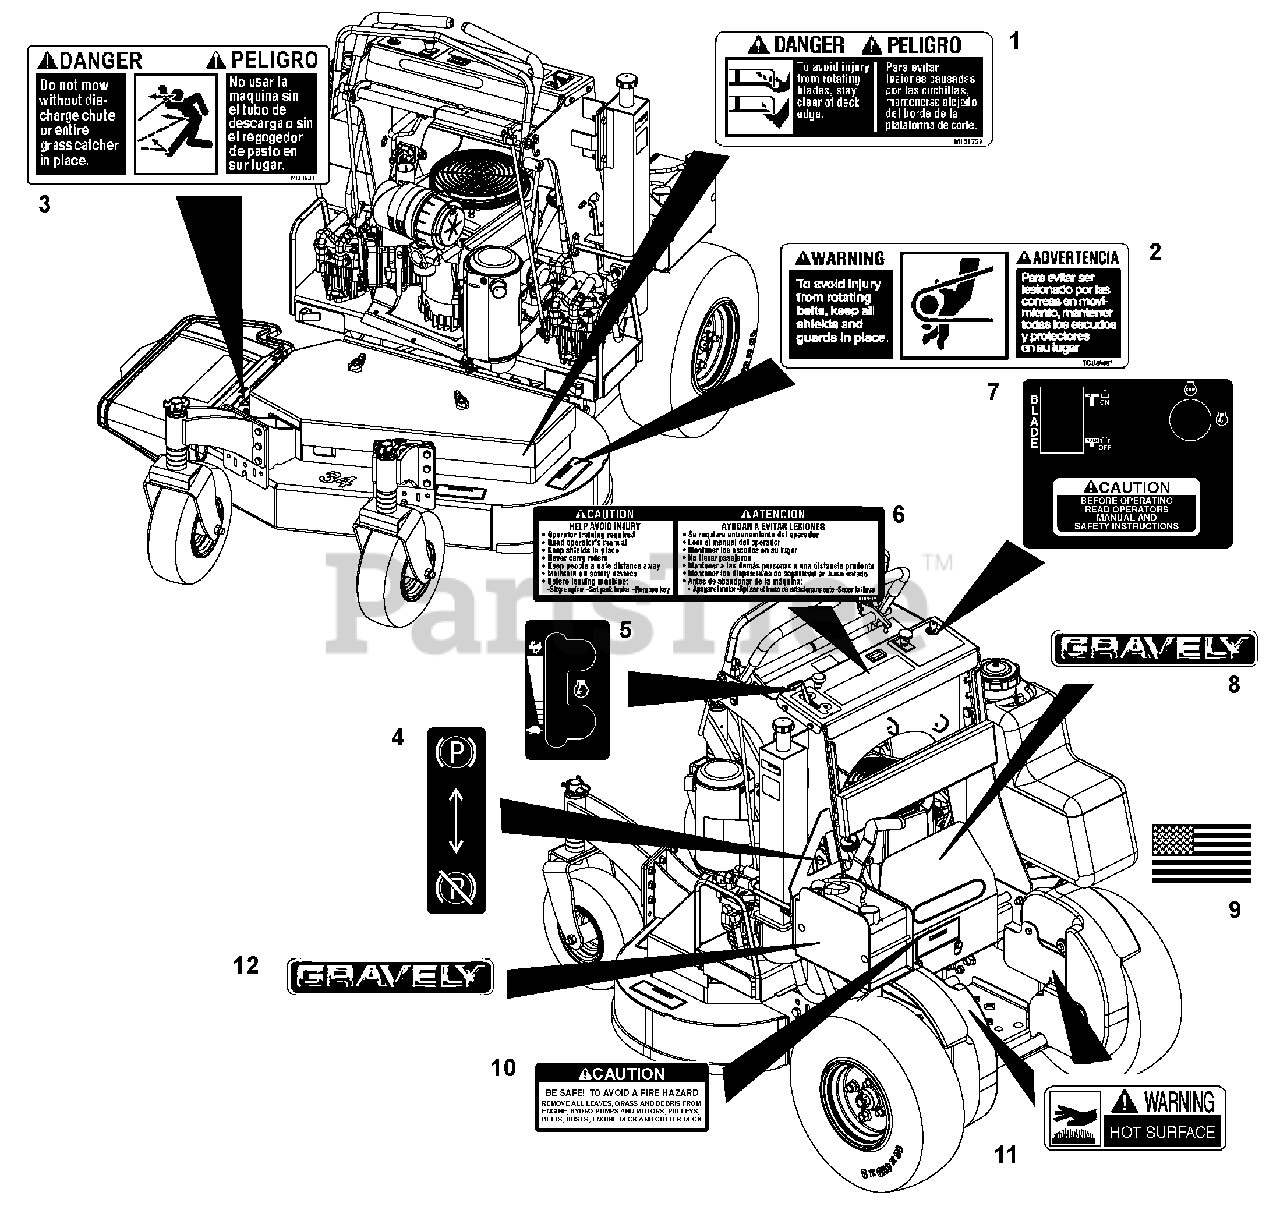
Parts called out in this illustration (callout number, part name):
1	Decal, Danger - Blade Contact
2	Decal, Danger - Rotating Belts
3	Decal, Danger - Rotating Blades
4	Decal, Park Brake
5	Decal, Throttle
6	Decal, General Caution
7	Decal, PTO/Ignition
8	Decal, 15" Gravely Logo
9	Decal, American Flag
10	Decal, Caution - Fire Hazard
11	Decal, Warning, Hot Surface
12	Decal, Gravely Logo
